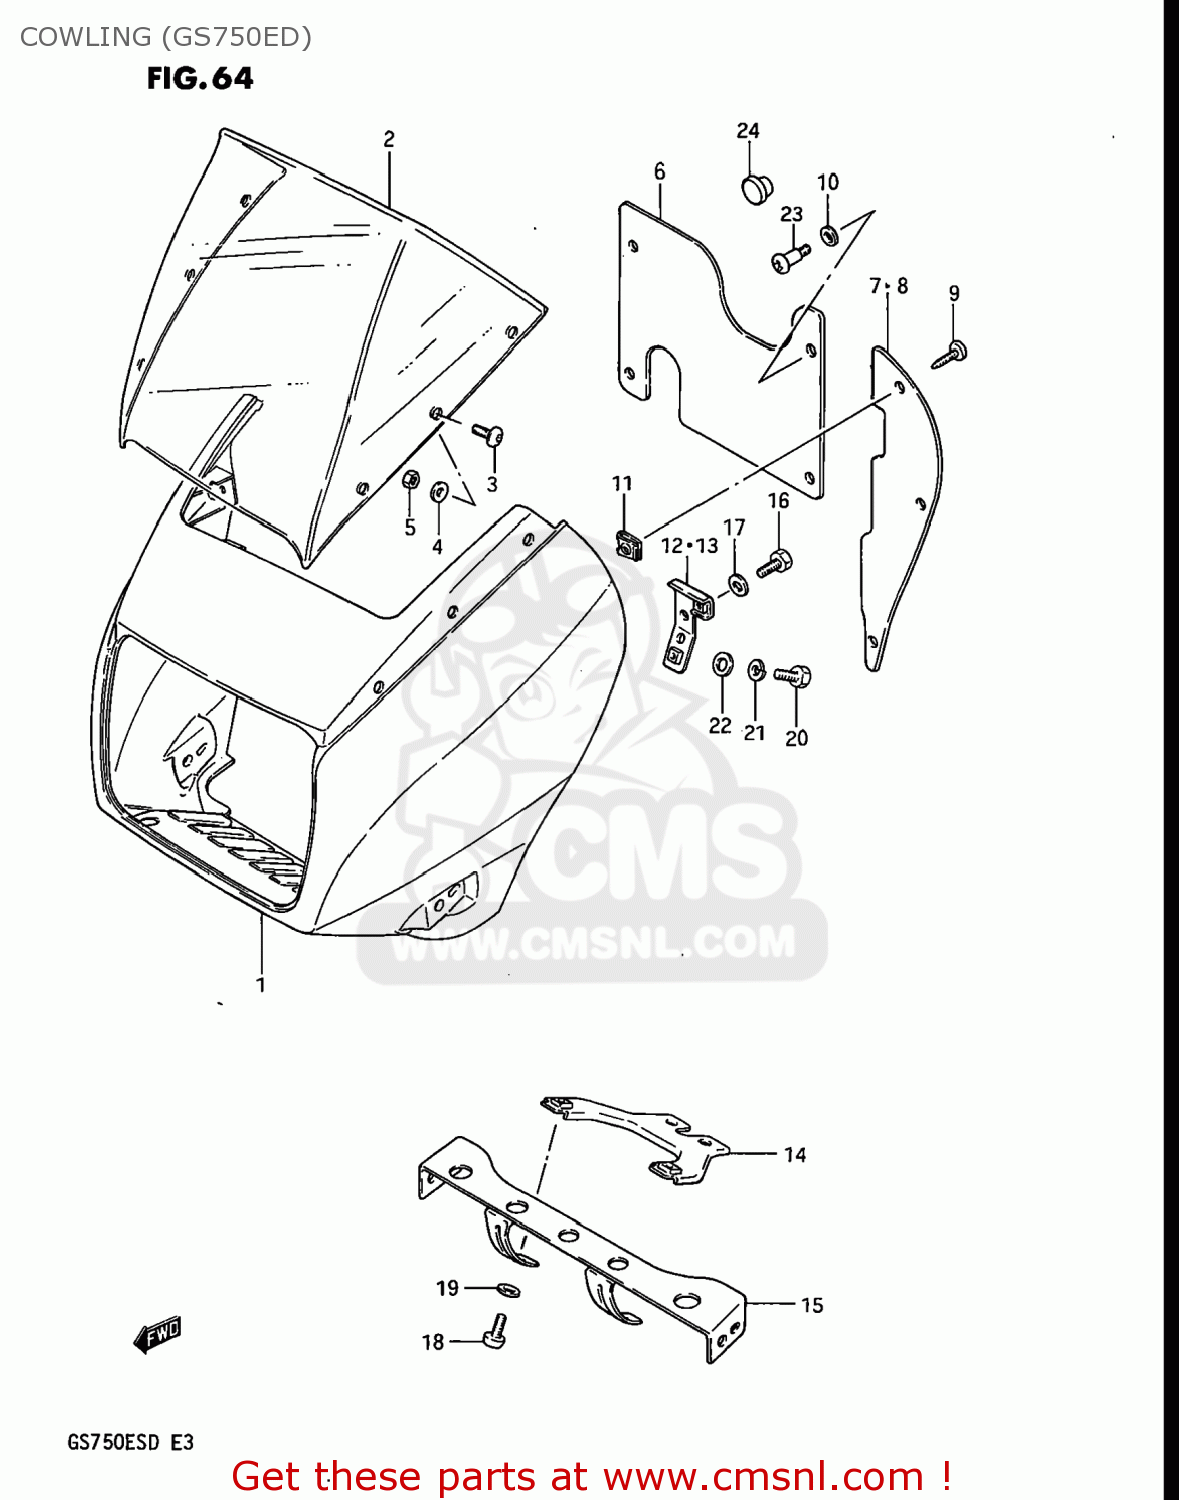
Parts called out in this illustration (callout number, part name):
1	COWLING ASSEMBLY
2	WINDOW,COWLING
3	SCREW(5X12)
4	WASHER
5	NUT
7	PANEL,COWLING SIDE,RIGHT
8	PANEL,COWLING SIDE,LEFT
9	SCREW
10	WASHER
11	NUT
12	BRACKET,COWLING,RIGHT
13	BRACKET,COWLING,LEFT
14	BRACKET,COWLING,LOWER
15	BRACE,COWLING,LOWER
16	BOLT, UPPER
17	LOCK WASHER
18	SCREW 6X12
19	LOCK WASHER
20	BOLT, UPPER
21	LOCK WASHER
22	WASHER (6.5X18X1.6)
23	SCREW
24	PLUG(OD:12)
